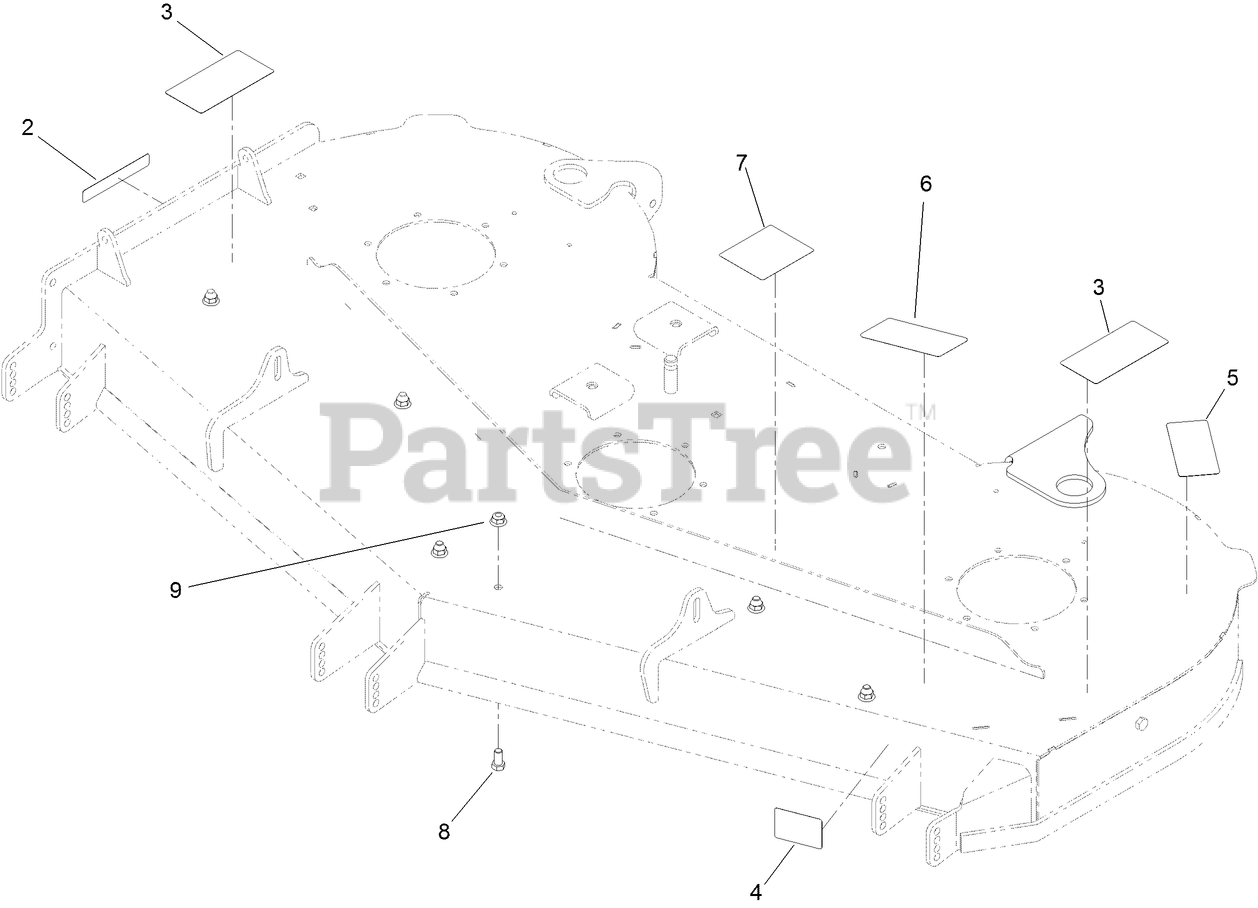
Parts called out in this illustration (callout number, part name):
2	DECAL-DANGER
3	DECAL-DANGER
4	DECAL-SCALP, ANTI
5	DECAL-TORQUE, BLADE BOLT
6	DECAL-DECK, 60 INCH
7	DECAL-ROUTING, BELT
8	SCREW-HH
9	NUT-HF, NI
